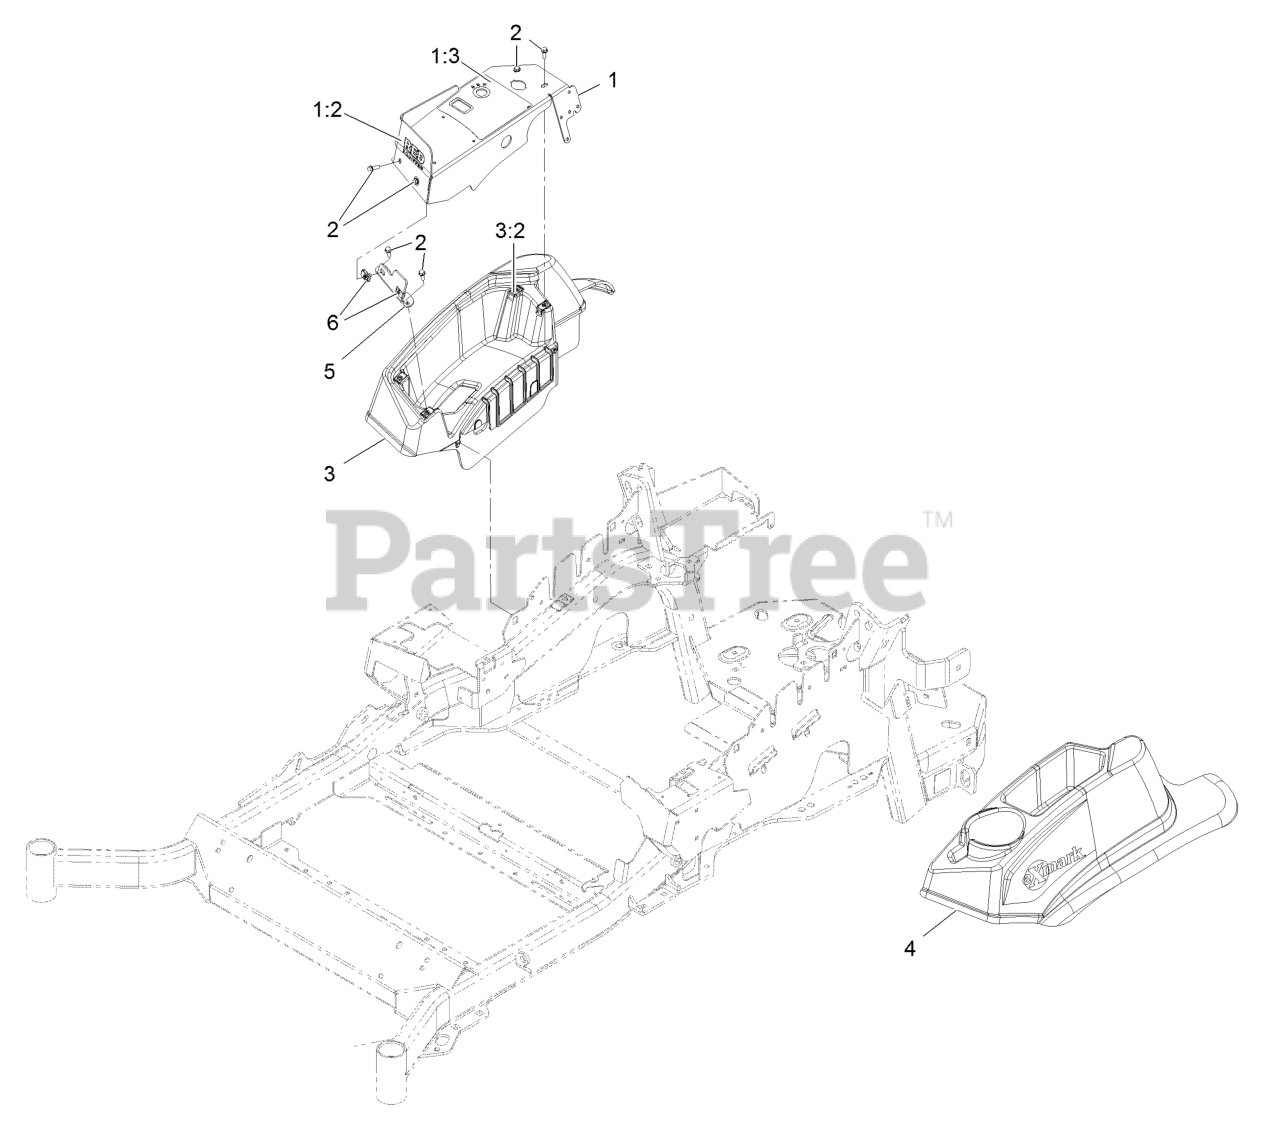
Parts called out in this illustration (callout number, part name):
1	Cover Panel ASM W/Decals
1:2	Decal-Control Panel Red
1:3	Decal-Console
2	Screw-Machine 1/4-20 X 3/4
3	Console,RH As ASM
3:2	Nut-Retainer-Panel 1/4-20
4	Console, LH As
5	Bracket-Console
6	Nut-Retainer-Panel 1/4-20
